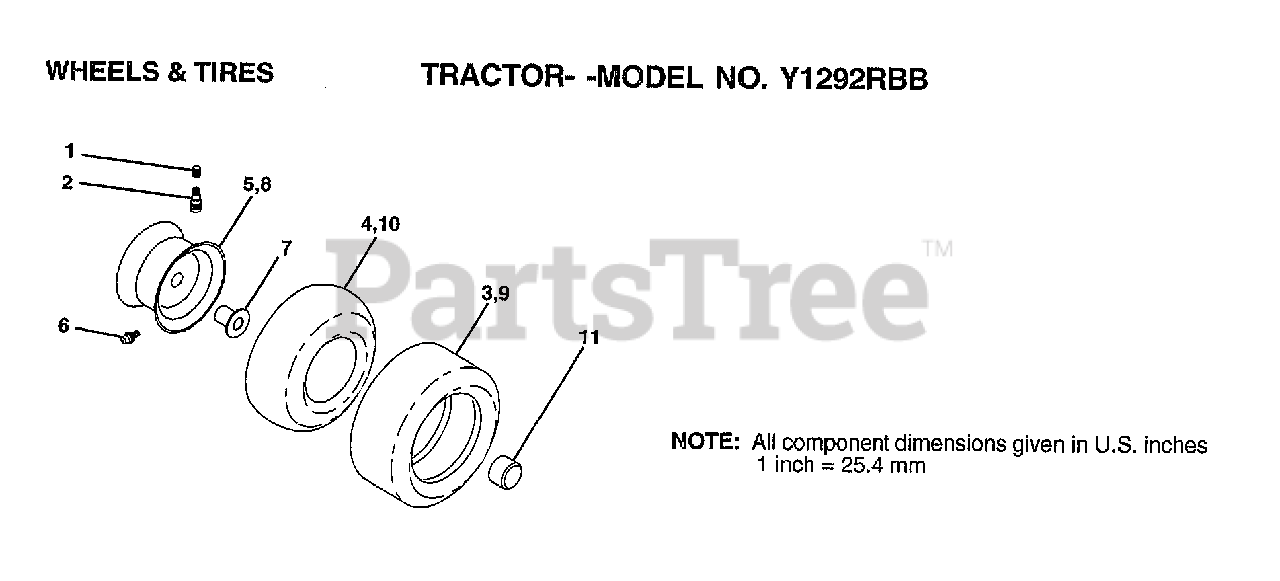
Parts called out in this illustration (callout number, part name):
1	VALVE CAP
2	VALVE STEM LT
4	TUBE.5.3/4.5/6
5	"RIM,FRT T"
6	FITTING LT
7	"FLANGE, BEARING"
8	"RIM 8"""
10	TUBE.18X9.5-8
11	HUB CAP
